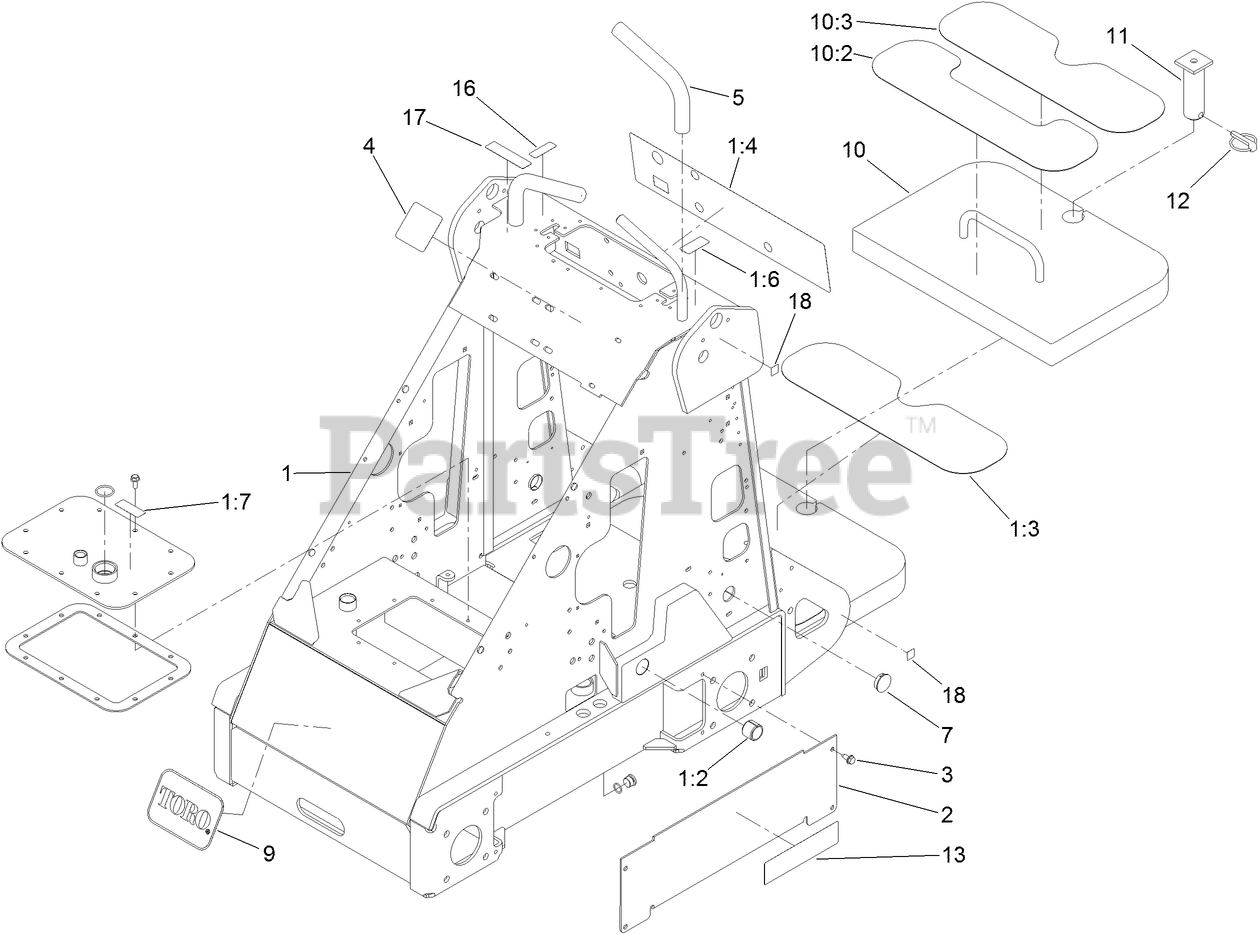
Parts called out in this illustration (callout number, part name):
1	FRAME ASM
1:2	BUSHING-TENSION
1:3	TREAD-FOOT
1:4	DECAL-PANEL, CONTROL
1:6	DECAL-THROTTLE
1:7	DECAL-OIL, HYD
2	COVER-HOSE
3	SCREW-HWHTF
4	DECAL-SELECTOR, SPEED
5	GRIP-CUSHION
7	PLUG-HOLE
9	DECAL
10	COUNTERWEIGHT ASM
10:2	TREAD-FOOT
12	PIN-LYNCH
16	DECAL-CHOKE
17	DECAL-ARRESTER, SPARK
18	DECAL-POINT, LIFT
